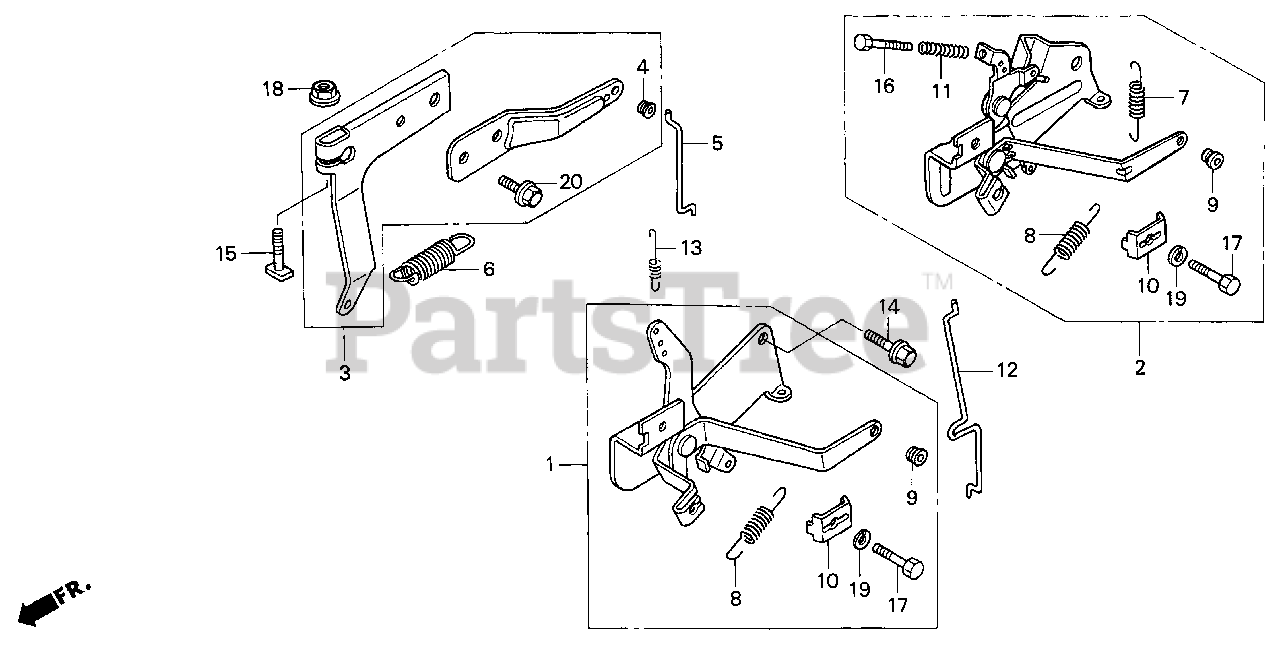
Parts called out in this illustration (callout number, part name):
3	ARM, GOVERNOR
4	COLLAR, LEVER
5	ROD, GOVERNOR
6	SPRING, GOVERNOR
7	SPRING, LEVER
8	SPRING, CONTROL LEVER RETURN
9	COLLAR, LEVER
10	HOLDER, CABLE
11	SPRING, CONTROL ADJUSTING
12	ROD, CHOKE
13	SPRING, THROTTLE RETURN
14	BOLT, FLANGE (6X14)
15	BOLT, GOVERNOR ARM
16	BOLT, RECESSED (5X34)
17	BOLT, RECESSED (5X16)
18	NUT, FLANGE (6MM)
20	BOLT, FLANGE (6X8)
